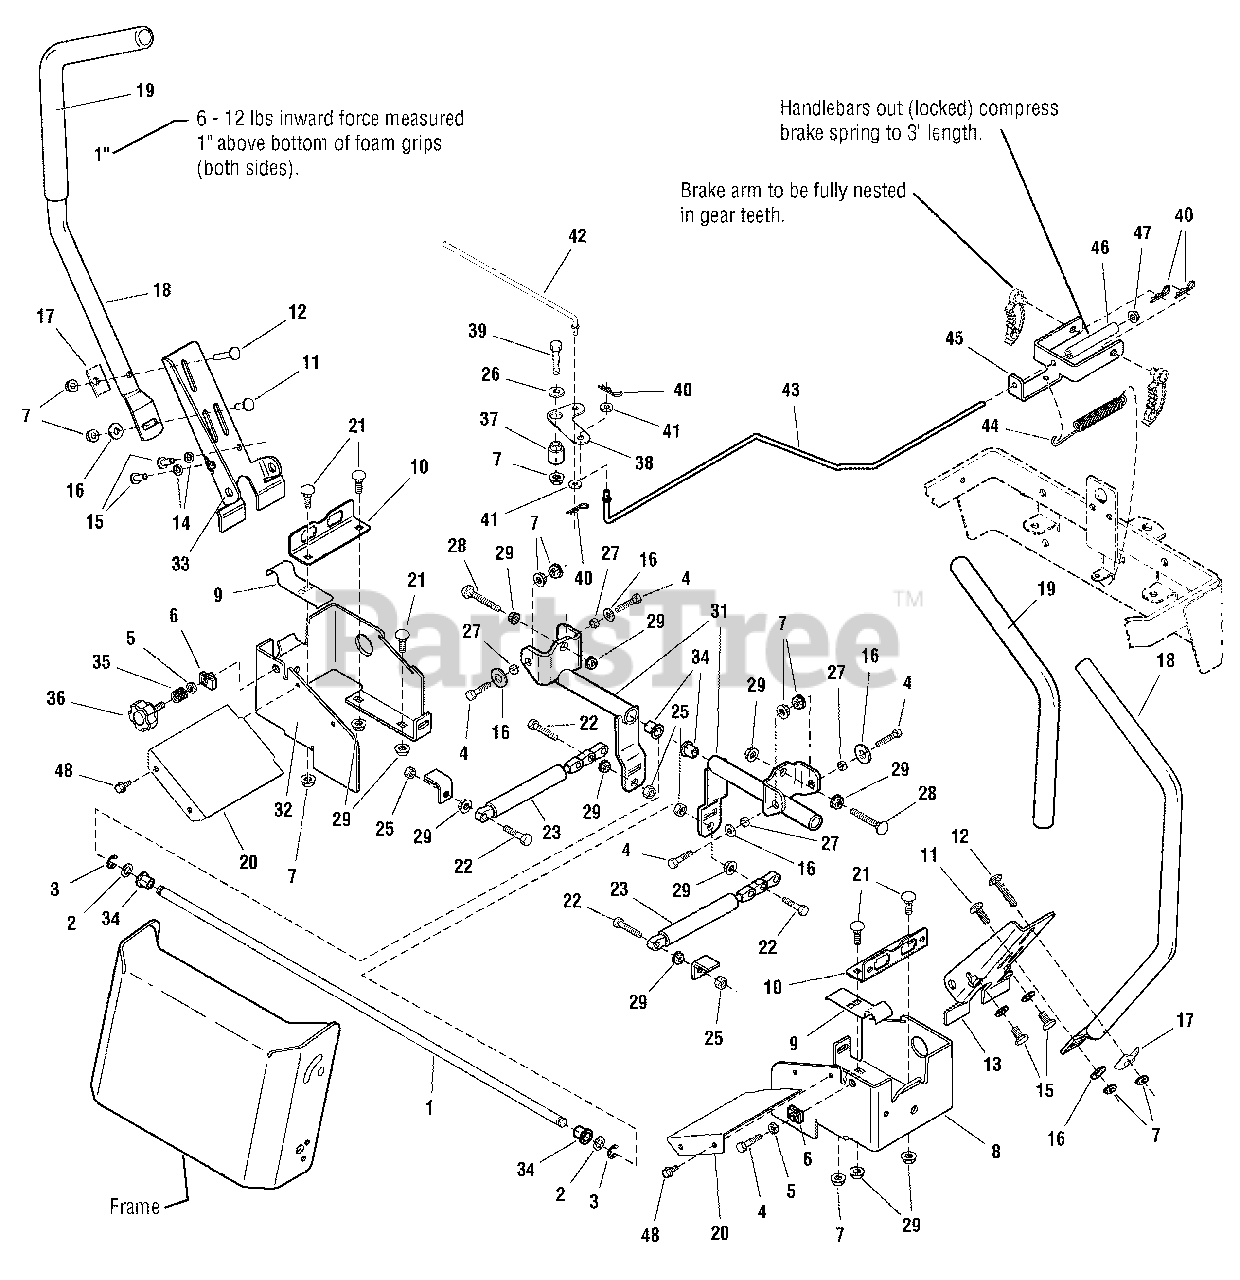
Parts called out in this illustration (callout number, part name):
1	SHAFT, Cross
2	WASHER, 1/2
3	RING, Klipring Extension
4	CAPSCREW, Hex Head, 5/16-18 x 1 1/4
5	NUT, Hex Jam, 5/16-18
6	NUT, Speed, 5/16-1
7	NUT, Hex Flange, 5/16-18 ESNA
8	BRACKET, L.H. Mounting Handle Pivot
9	CLIP, Brake
10	BRACKET, "L" Switch
11	BOLT, Carriage, Short Neck, 5/16-18 x 1
12	CARRIAGE BOLT, 5/16-18 x 1-3/4, G5
13	BRACKET, Tube Mount L.H.
14	LOCKWASHER, Spring, 5/16
15	SCREW, Truss Head Torx Drive, 5/16-18 x 7/8
16	WASHER, 5/16
17	CLAMP, Saddle Snow Handle, E-Coat
18	TUBE, Handle
19	GRIP, Foam Handle
20	COVER, Lower Handle
21	BOLT, Carriage, 5/16-18 x 1 1/4
22	CAPSCREW, Hex Head, 5/16-18 x 1-1/2, G5
23	SHOCK ABSORBER
25	NUT, Hex Lock ESNA Light, 5/16-18NC-3B
26	WASHER, 5/16
27	SPACER, Powdered Metal
28	CARRIAGE BOLT, 5/16-18 x 2-1/4, G5
29	NUT, Hex Flange Whiz Lock, 5/16-18
31	PIVOT ASSEMBLY, Control
32	BRACKET, R.H. Mounting Handle Pivot
33	BRACKET, Tube Mount R.H.
35	SPRING, Compression
36	KNOB, Extension Thread, 5/16-18 x 1-1/4
37	BUSHING, Powdered Metal
38	BRACKET, Pivot
39	SCREW, Hex Head Cap, 5/16-18 x 1 3/4
40	PIN, Quick
41	WASHER, 1/4
42	ROD, Pivot
43	ROD, 1/4-20 x 2
44	SPRING, Extension
45	BRACKET, Duel Brake
46	SPRING, Compression
47	NUT, Hex Flange, 1/4-20 ESNA
48	SCREW, Hex Washer Head Taptite, 1/4-20 x 1/2
